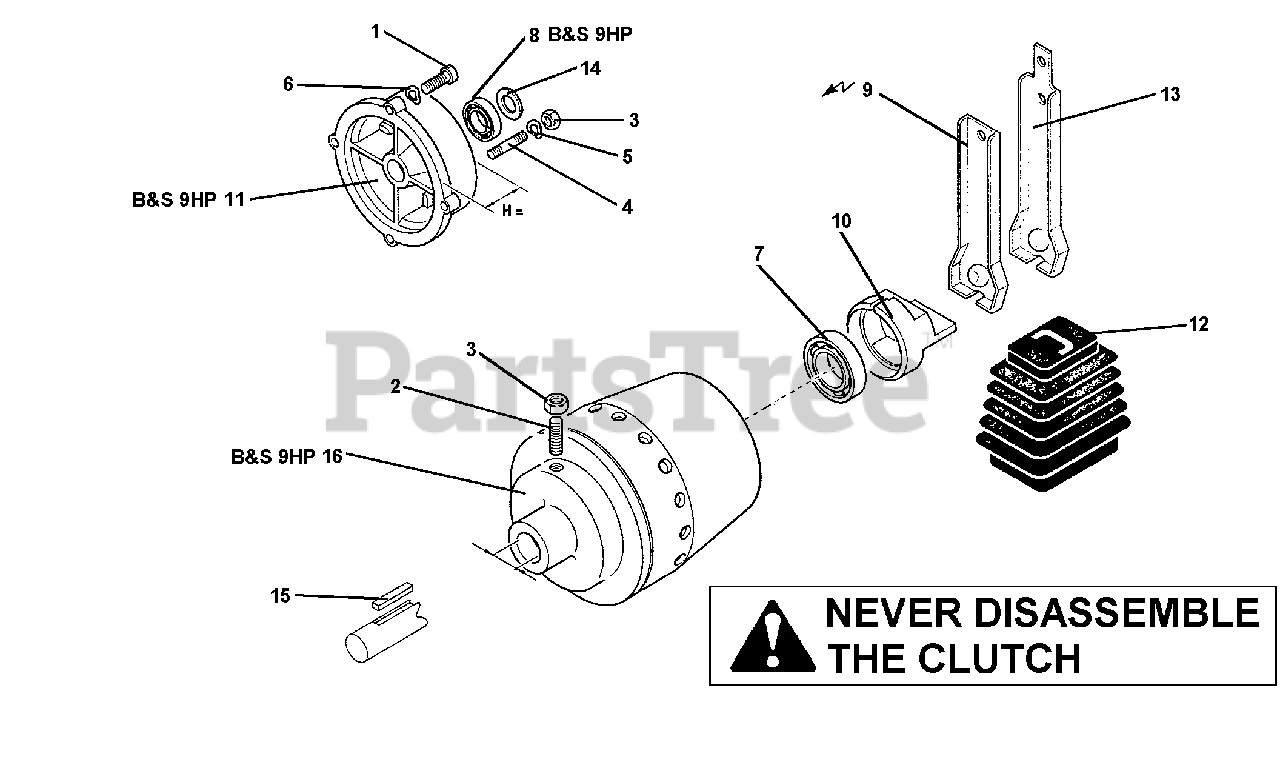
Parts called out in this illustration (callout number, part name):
1	SCREW 7/16 X 1 1/4"
2	SET SCREW M8X30
5	WASHER, WAVE
7	BEARING 17X40X12
8	BEARING, 30X55X13
9	CLUTCH LEVER, ELECTRIC START
10	CONE PUSHER
11	FLANGE, 9HP B&S
13	CLUTCH LEVER, RECOIL START
16A	HEAVY DUTY CLUTCH, 9HP B&S
16B	HEAVY DUTY CLUTCH KOHLER
